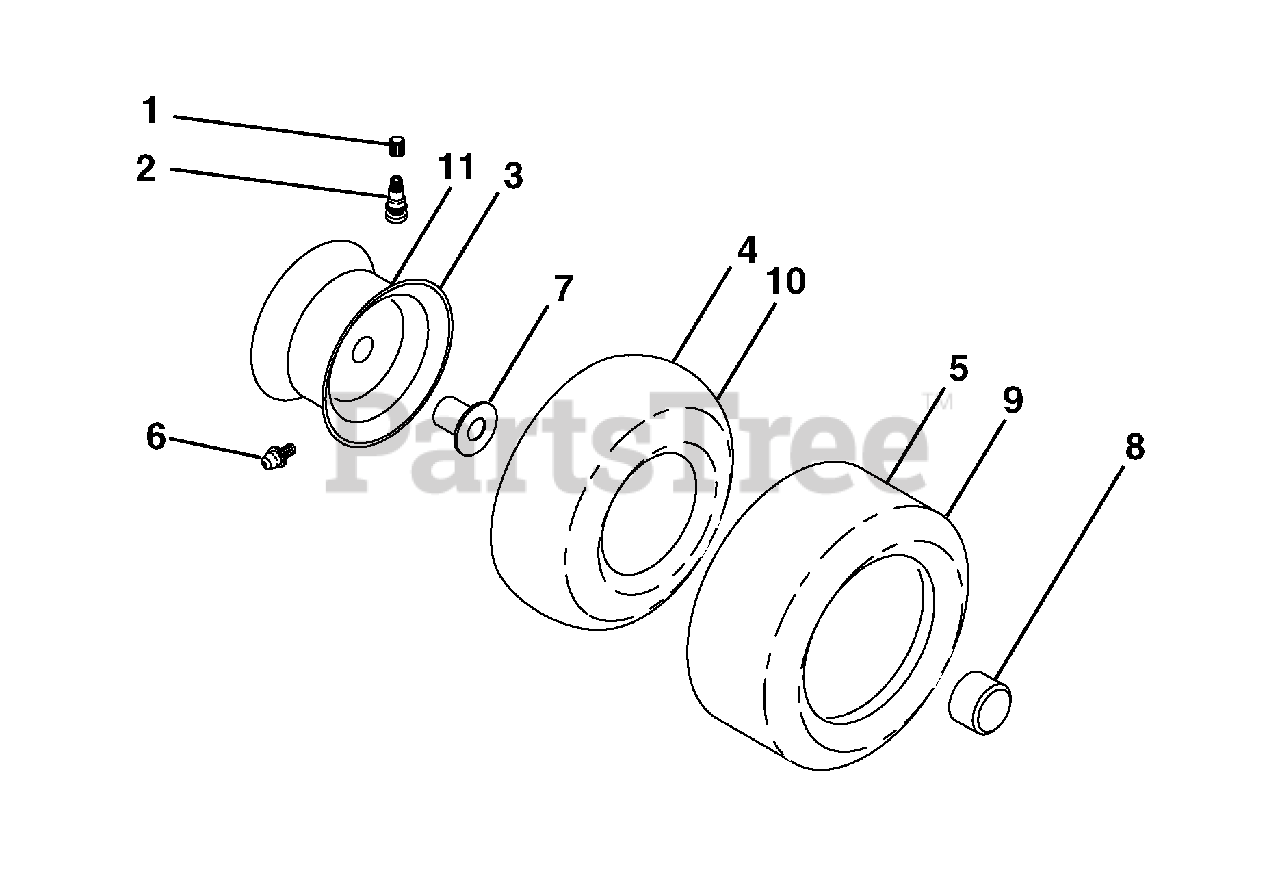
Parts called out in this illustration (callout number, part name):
1	Cap, Valve, Tire
2	Stem, Valve
3	Rim Assembly, Front
4	Tube, Front
5	Tire, Front 15 x 6-6
6	Fitting, Grease
7	Bearing, Flange
8	Cap, Axle (Front Wheel Only)
9	Tire, Rear 20 x 8-8
10	Tube, Rear
11	Rim Assembly, Rear
